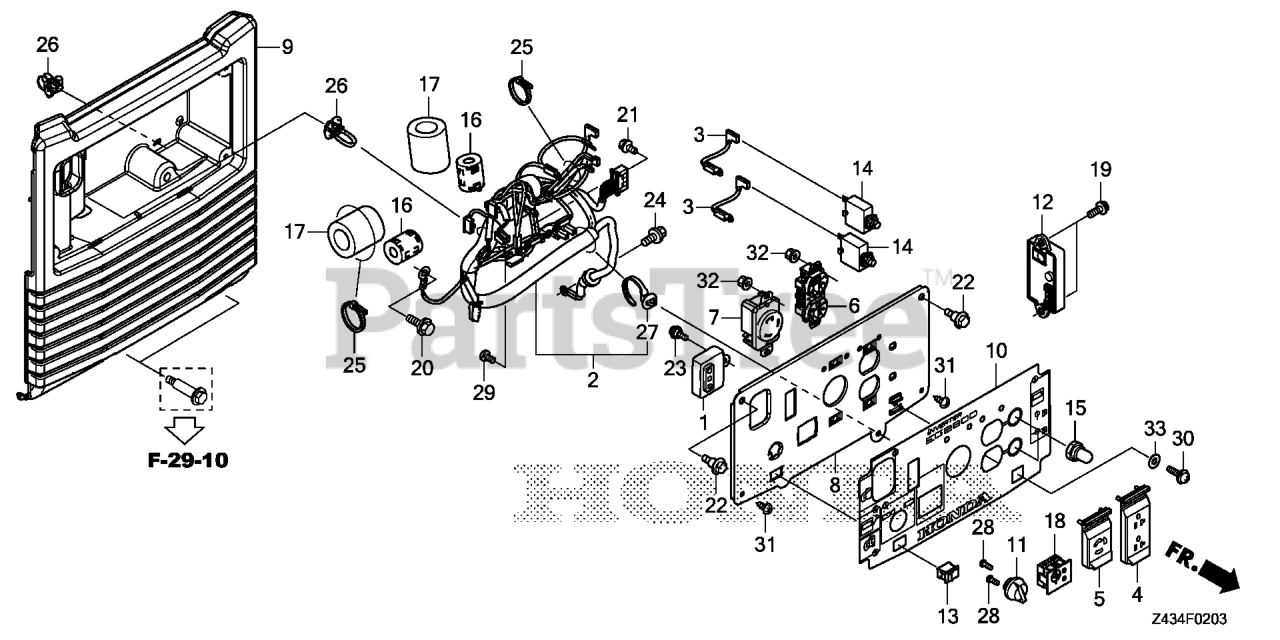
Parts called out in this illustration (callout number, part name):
1	IGNITION UNIT
2	WIRE HARNESS ASSY., CONTROL
3	WIRE, TERMINAL (150MM)
4	COVER, RECEPTACLE (20A-125V)
5	COVER, RECEPTACLE (30A-125V)
6	RECEPTACLE (20A/125V)
7	RECEPTACLE (30A/125V)
8	PANEL, CONTROL
9	CASE, CONTROL PANEL *R280* (POWER RED)
10	MARK, CONTROL PANEL
11	SWITCH ASSY., ENGINE STOP
12	SENSING UNIT (CO)
13	SWITCH, AUTO THROTTLE
14	PROTECTOR, CIRCUIT (20A) (WHITE)
15	COVER, CIRCUIT PROTECTOR
16	FILTER, SUB NOISE (AC)
17	SUPPORTER, FILTER
18	LED ASSY., INDICATER
19	BOLT, FLANGE (5X14)
20	BOLT, FLANGE (6X14)
21	SCREW, TAPPING (5X12)
22	BOLT, CONTROL PANEL
23	SCREW, PAN (5X13)
24	BOLT, GROUND (6X12) (SN)
25	TIE, CABLE
26	CLIP, WIRE HARNESS
27	CLIP, HARNESS BAND (145MM) (BLACK)
28	SCREW, PAN (3X8)
29	SCREW, PAN (5X8)
30	SCREW, PAN (5X16)
31	SCREW, TAPPING (5X12)
32	NUT, FLANGE (4MM)
33	WASHER, PLAIN (5MM)
